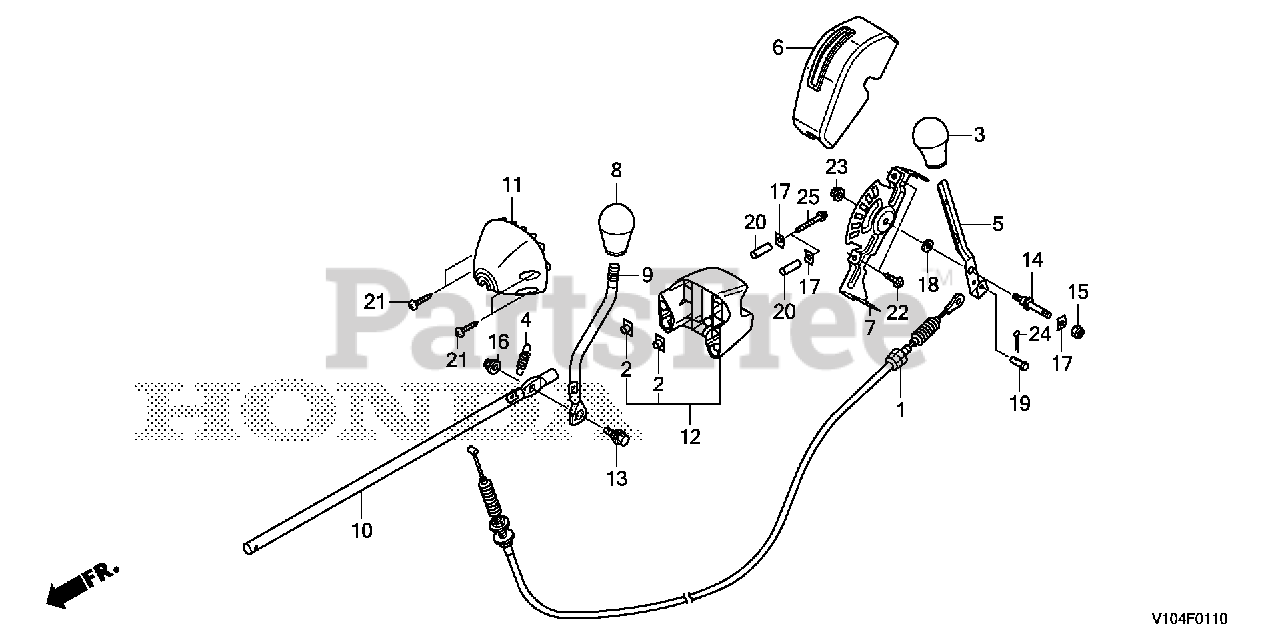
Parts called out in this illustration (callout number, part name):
1	CABLE, CHUTE GUIDE
2	NUT, SPECIAL (6X7)
3	GRIP, SHUTTER ADJUST *NH164* (GRIP GRAY)
4	SPRING, CHUTE CONTROL
5	LEVER, CHUTE GUIDE
6	COVER, CHUTE GUIDE
7	PLATE, CHUTE GUIDE
8	GRIP, CHUTE HANDLE
9	HANDLE, CHUTE
10	ROD, CONTROL
11	CASE, FR. CHUTE
12	CASE, FR. CHUTE
12	CASE, RR. CHUTE
13	BOLT, SHOULDER
14	BOLT, CHUTE GUIDE
15	NUT, NYLON LOCK (6MM)
16	NUT, FLANGE (8MM)
17	WASHER, FRAME JOINT
18	WASHER (10.4MM)
19	PIN, CABLE JOINT
20	COLLAR, BATTERY MOUNTING
21	SCREW, TAPPING (4.2X32) (PO)
21	SCREW, TAPPING (4X20) (PO)
22	SCREW, TAPPING (5X12) (PO)
23	NUT, FLANGE (6MM)
24	PIN, COTTER (1.6X12)
25	BOLT, FLANGE (6X40)
